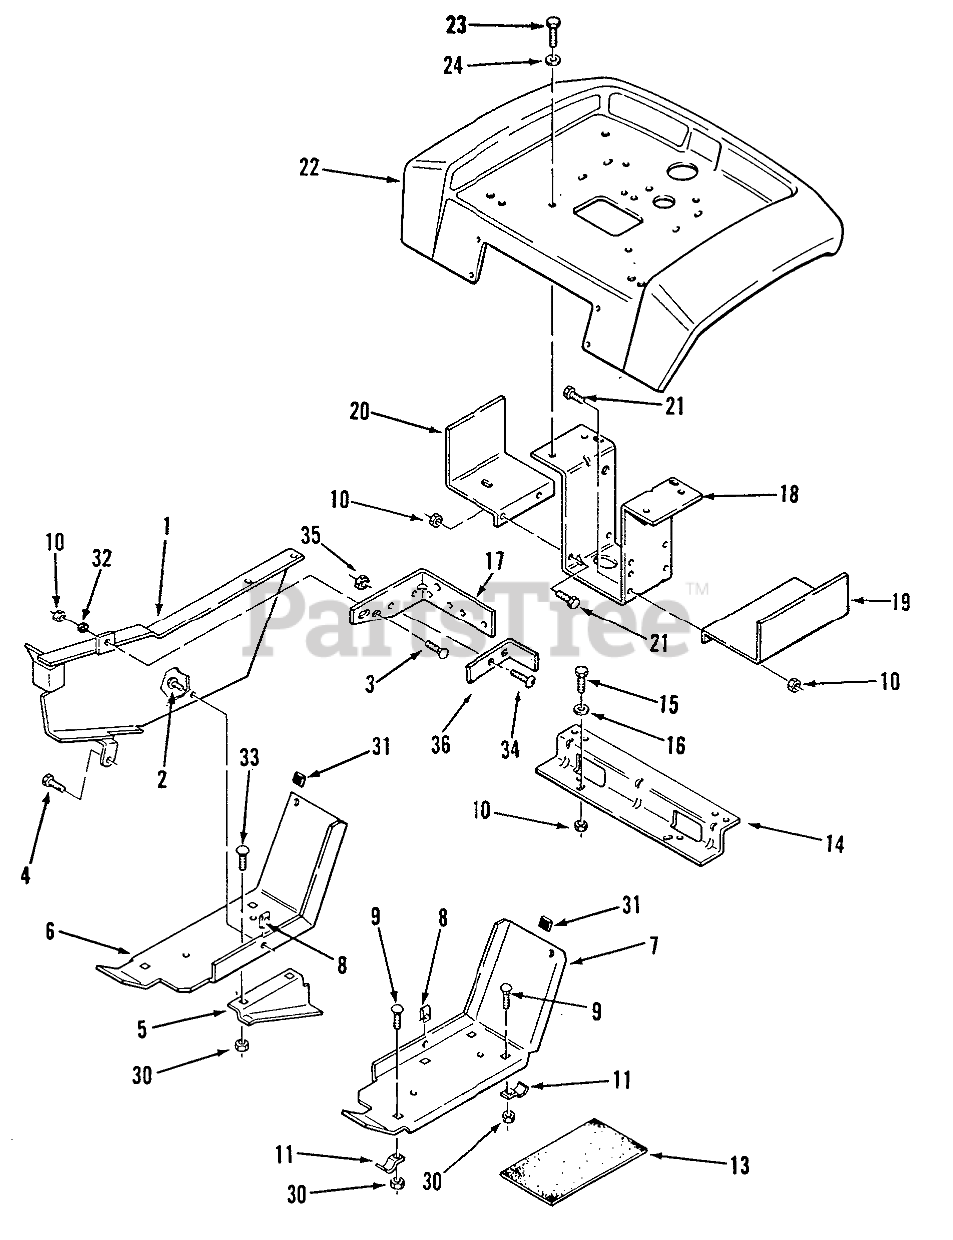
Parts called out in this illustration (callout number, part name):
1	Belt Guard
2	Screw
3	Bolt
4	SCREW
5	GUID-LOWER BLTR
6	Footrest-RH
7	FOOTREST LH R
9	Bolt
10	Nut
11	BRACKET
13	PAD FOOTREST
14	BRACKET-FENDER B
15	Bolt
16	WASHER 5/16 SAE
17	SUPPORT-BELT GUAR B
18	Bracket-Fender Support
19	Fuel Tank Support LH
20	Support-FueITank RH
21	Bolt
22	Fender
23	SCREW
24	WASHER 5/16 SAE
30	Nut
31	BUMPER
32	NUT-PUSH
33	Bolt-Carriage
34	HWHMS 10-24 X 5/8
35	Nut
36	BRACKET FUSE
